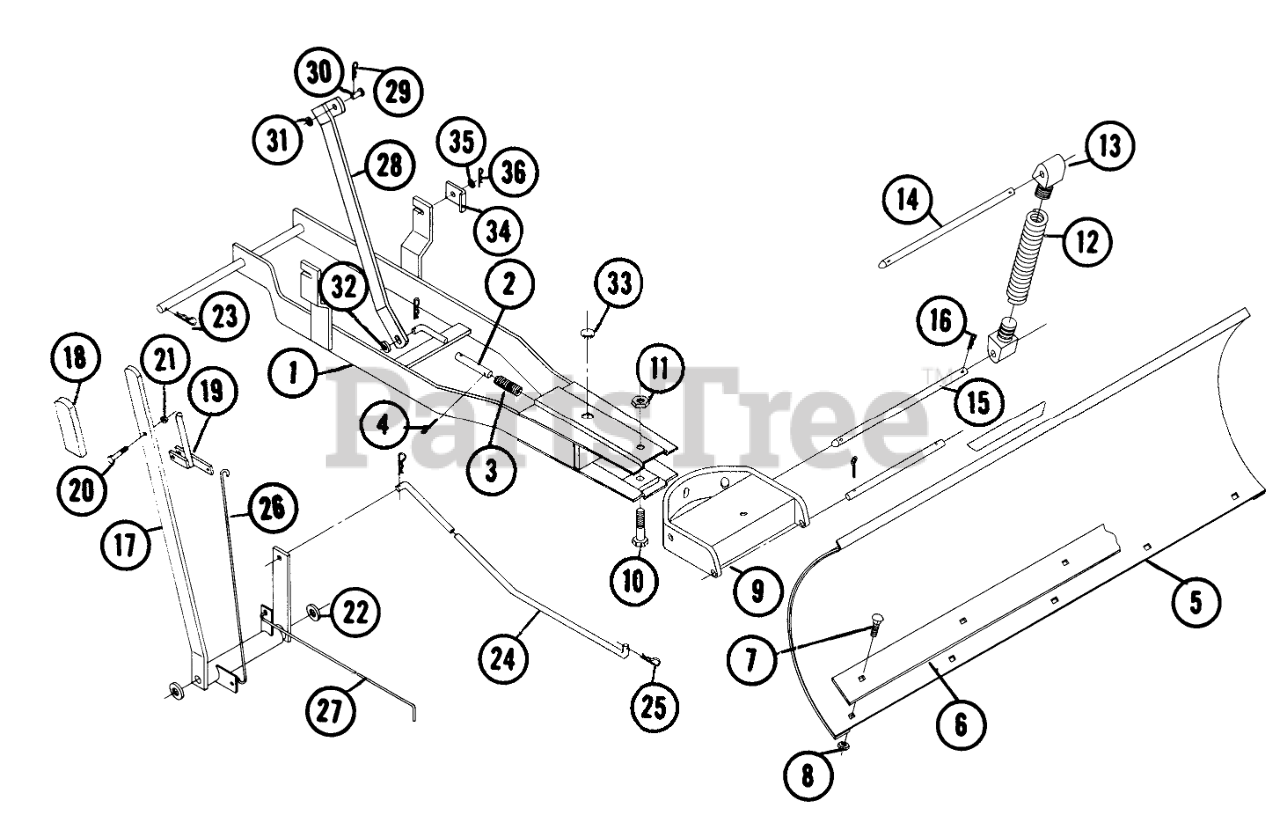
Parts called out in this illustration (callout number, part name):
1	Frame
2	Index Pin
3	SPRING-COMPRESSION
5	Blade
6	Plate
7	Bolt-Carriage
8	NUT
9	Sector and Channel
10	Bolt
11	Nut
12	Spring
13	Lug
14	ROD-PIVOT, BLADE
15	ROD-LOWER
16	Hairpin
17	Index Lever
18	GRIP
19	LEVER ASSY
20	Bolt
21	Nut
22	Washer
23	Hairpin
24	Brake Pedal
25	Hairpin
26	Upper Index Rod
27	LOWER INDEX ROD
28	Lift Bar
29	Hairpin Cotter
31	Washer
32	WASHER
33	PLUG
33	Caution Decal
33	DECAL-WHEEL HORSE
35	Washer
36	Hairpin Cotter
